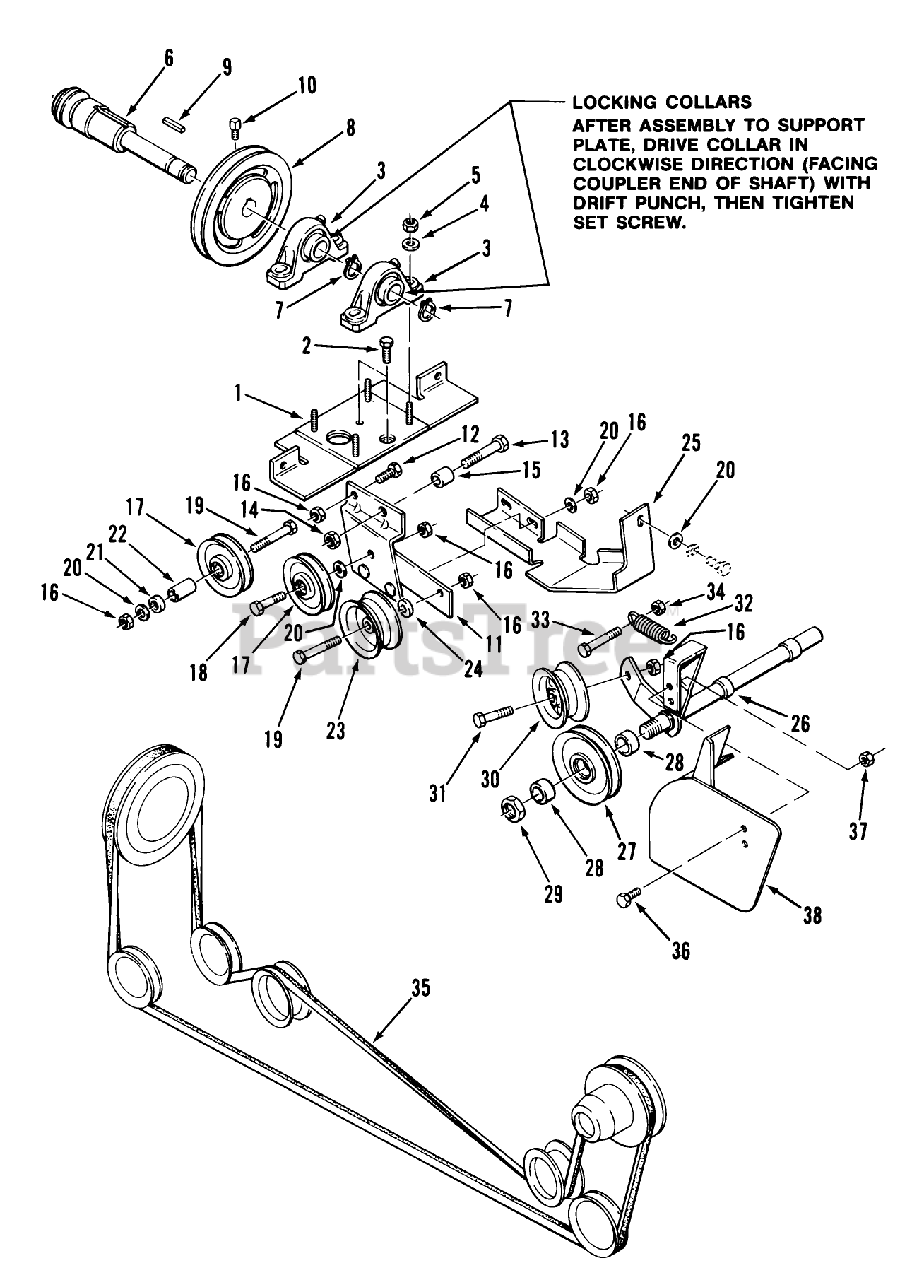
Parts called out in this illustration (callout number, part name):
4	WASHER
5	NUT-HEX
9	KEY-SQUARE
10	Sq. Hd. Set Screw 5/16-18 x 5/8
11	Rear Idler Support Bracket
15	Spacer 1/2" Bore, 1 7/64" Long
23	PULLEY-IDLER
28	SPACER
32	SPRING-BRAKE
